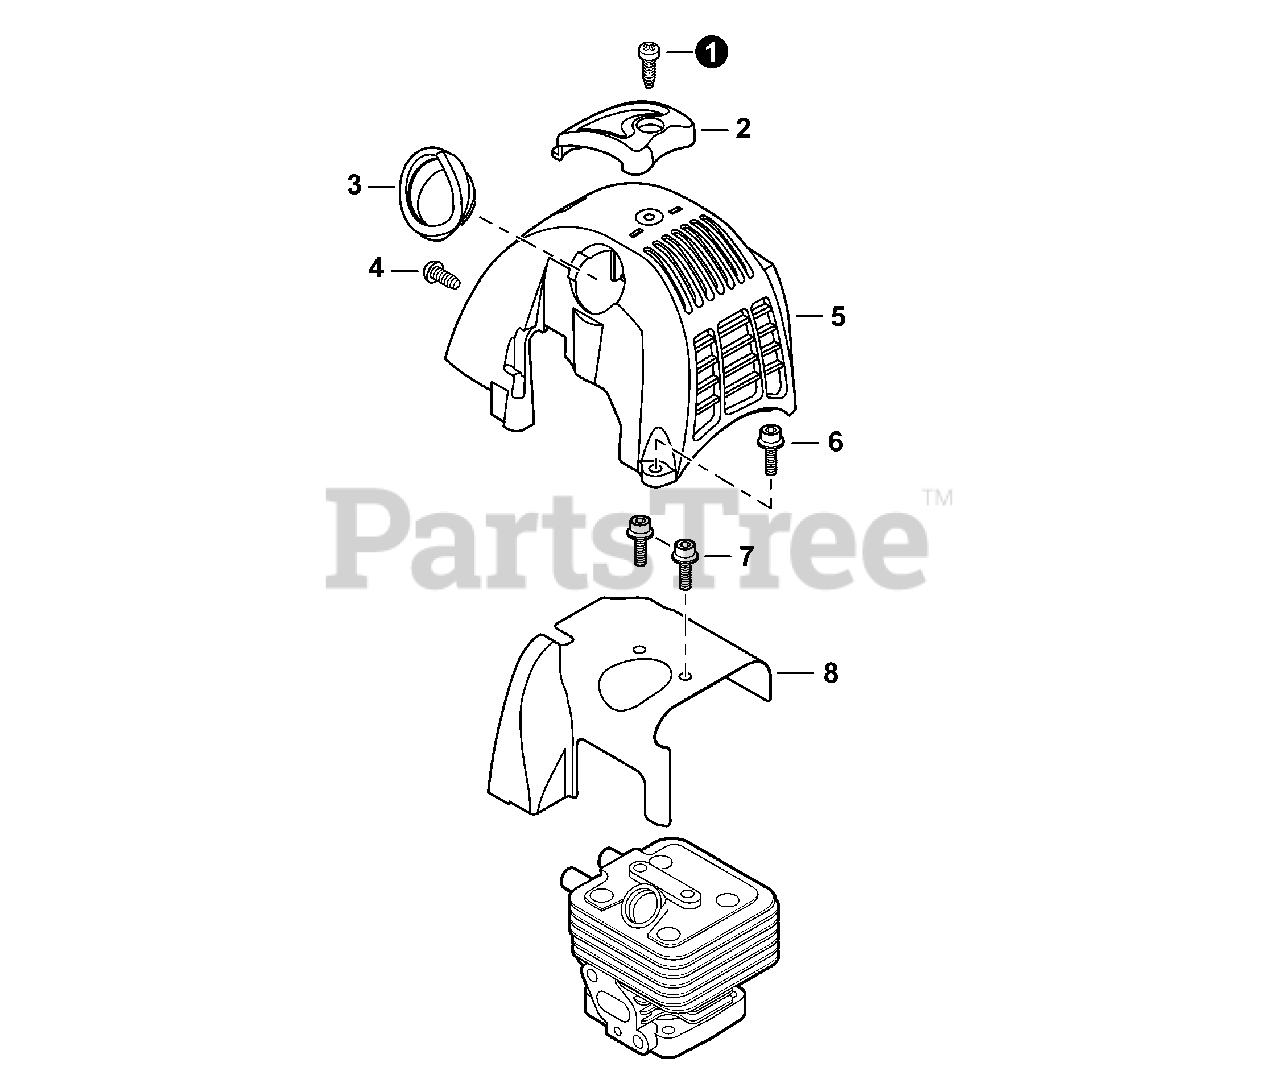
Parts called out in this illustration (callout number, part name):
1	SCREW, TAPPING 5x16
2	GUARD, TOP
3	GUARD, TOP - SPARK PLUG
4	BOLT 5x12
5	COVER, ENGINE
6	BOLT 5x14
7	BOLT 5x8
8	SHIELD, CYLINDER
